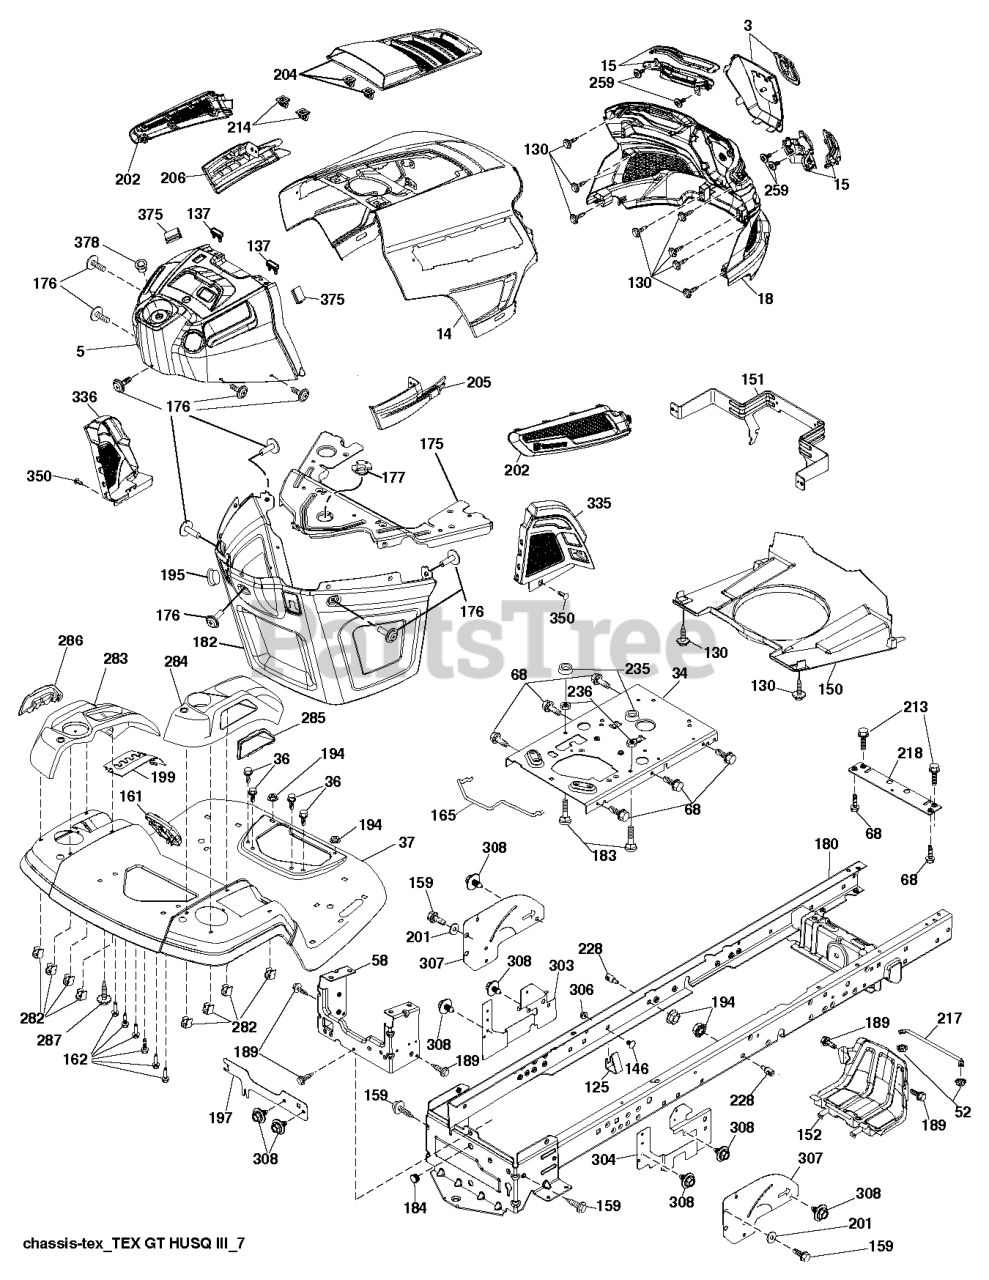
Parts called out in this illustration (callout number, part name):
5	DASHBOARD.UPPER.ASM.GT2.498
14	HOOD.ASM.HUSQVARNA.GT.TEX.ORAN
15	Service Kit
34	PLATE.ENGINE.WELDED.CHASSIS
36	SCREW 5/16"
37	FENDER.TLT.FS.W/CPH/FW/RSF.668
58	DRAWBAR UPPER 2PC SMALL FENDER
125	CLIP.FUEL.LINE
137	BUMPER DASH
146	BOLT.RDHD.SHT.SQNK.3/8-16X5/8
150	AIR.DUCT.GTV.BLACK
151	BRACKET.PIVOT.HOOD.GT.HUSQ.II
152	SHIELD.BROWNING.PNT.GT.V2
159	SCREW, 3/8-16X3/4
161	WINDOW.FUEL.LT.HUSQ.TEX.498
165	SUPPORT.TANK.REAR.W/TEX
175	PLATE.PNT.CROSSMEMBER.HUSQ/PRE
176	SCREW.#10-24X5/8.RN.QU
177	BUSHING STEERING
180	CHASS.WLDMNT.TLT.12GA/2PC.20"
182	DASH.LOWER.COMMON.12V.ADAPTOR
184	PLUG.DEMO.625
189	SCREW
195	PLUG.HOLE.DASH.LOWER.12V.BLK
197	SHIELD.DRAWBAR.LT.REAR.TANK
199	PLATE.DECK.LIFT.HUSQ.LT
201	WASHER
202	Vents
205	SIDE.TRIM.RH.GT.HUSQ.II
206	SIDE.TRIM.LH.GT.HUSQ.II.GRAY
213	SCREW HEXAGON HEAD SCREW 5/16-
214	CLIP.RETAINER.TINNER.
217	ROD.PIVOT.HOOD
218	X-PIECE.HOOD.STOP.NON/
228	STUD.W/"D"ANTI-ROTATION
236	NUT.CENTERLOCK.5/16-
282	CLIP.RETAINER.CONSOLE.LT.HUSQ
283	CONSOLE.DECK.LIFT.R.SDFL.HUSQ
284	CONCOLE.CNTRL.PDL.HUSQ.LT.498
285	CONSOLE INSERT RH
286	CONSOLE.INSRT.LH.HUSQ.LT.BLACK
287	SCREW 1/4X20
303	SHIELD.LWR.LH.LTGT.NON30
304	SHIELD.LWR.RH.LTGT.NON30.NOTCH
306	NUT LOCK FLG 3/8-16 UNC
307	SHIELD.UPPER.LT.GT.ISO
308	BOLT.5/16-18UNCX3/4 W/SEMS.BLK
335	COVER.LOWER.DASH.RH.BLACK
336	COVER-LH.LOWER.DASH.GT2.BLACK
350	CLIP.X-MAS.TREE
375	BUMPER CLIP-ON. DASH 1"
378	BUSHING FLANGE; PLASTIC
